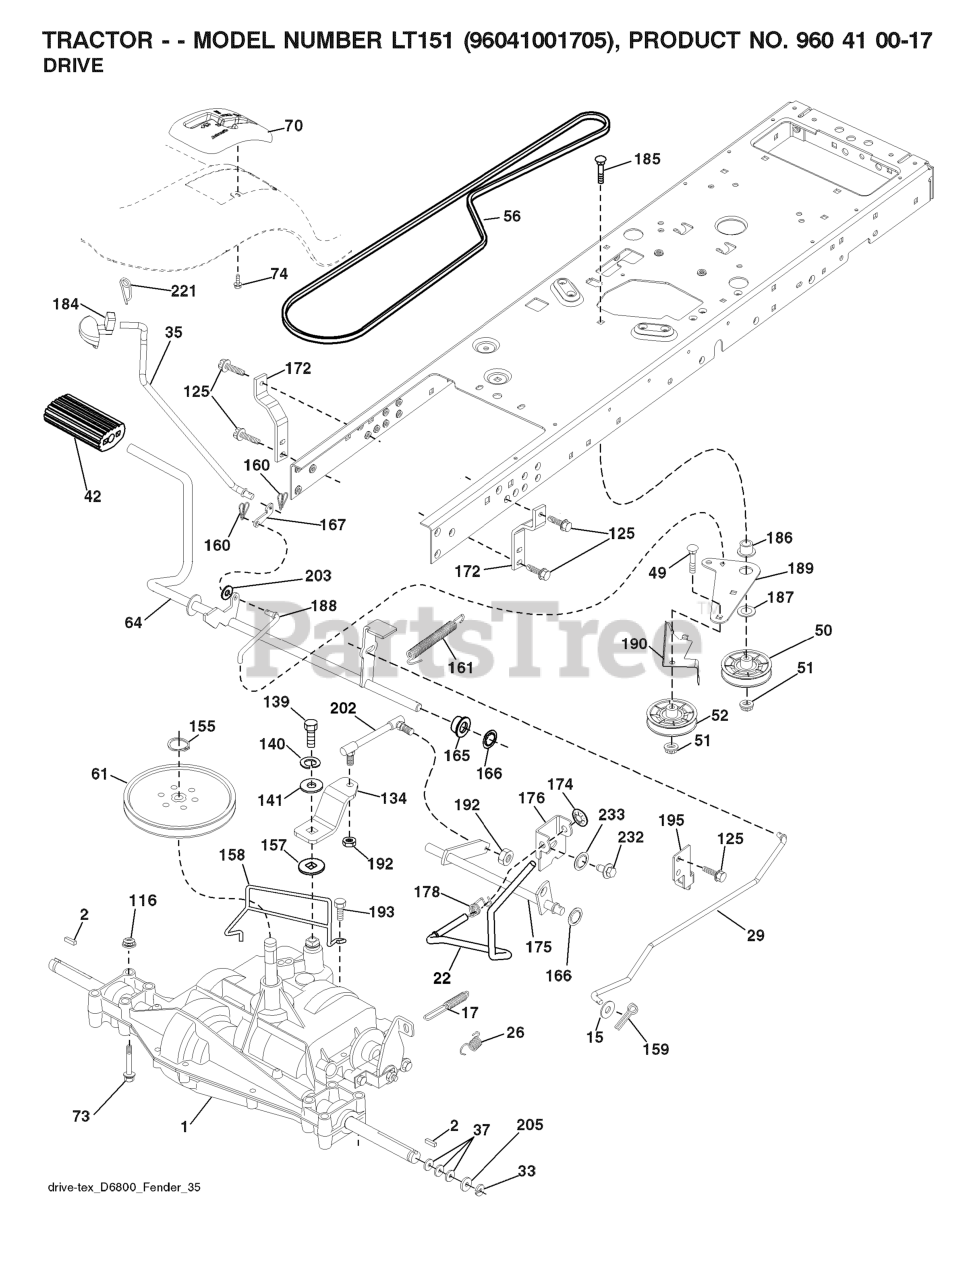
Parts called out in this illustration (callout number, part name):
2	SQUARE KEY
15	WASHER
17	SPRING.BRAKE.PEERLESS.TEX
22	ROD.SHIFT.FENDER.TLT.2006
23	KNOB.DUCKHEAD.1/2
26	SPRING.BRAKE.RTN.GR.DR
29	ROD.BRAKE.PEERLESS
35	ROD.CNTRL.PARK.PREDATOR.LT.TEX
42	PEDAL COVER T
50	IDLER.FLAT.910.OFFSET
51	NUT LOCK FLG 3/8-16 UNC
52	IDLER.V-GROOVE.910.OFFSET
61	PULLEY TRANS
64	SHAFT.ASM.PEDAL.BRAKE.
73	BOLT HEX 5/16-18 GR 5
116	NUT LOCK HEX FLANGE 5/16-18
125	SCREW
134	ARM.SHIFT.
139	BOLT 1/4-28X3/4
140	LOCKWASHER
155	RETAINING RING LT
157	WASH-SHFT PLT LT
158	KEEPER.PMS.18/20.D4365
159	COTTER PIN
160	RETAINER CLIP
161	SPRING.RETURN.CLUTCH.2006
165	BUSHING.SHAFT.BRAKE.HAND
166	NUT.PUSH.625.2006
167	LATCH.BRAKE.SPRING
172	STRAP.TRQ.LH.GEAR.DRIV
174	NUT.PUSH.500.2006
175	SHAFT.ASM.SHIFT.
176	ARM.CLEVIS.ROD.SHIFT
178	SPRING.SHIFT.GT2006
184	HANDLE PARKING BRAKE
186	SPACER.RETAINER
187	WASHER 12/32X2X10GA
188	RP.LINK.CLUTCH.GROUND.DRIVE
189	BELLCRANK.GROUND.DRIVE.TEX.
190	KEEPER.BELLCRANK.DRIVE
192	NUT LOCK CENTER 1/4 -28 FNTHD
193	SCREW 5/16"
195	BRKT.ROD.BRAKE.PEERLES
202	LINK.TRANSAXLE.D6800.18/20"TEX
203	WASHER
221	RETAINER.SPRING.CLIP.H
226	BOLT FIN HEX 7/16-14 X 1
227	WASHER SERRATED
231	IDLER.V-GROOVE.1.688.OFFSET
